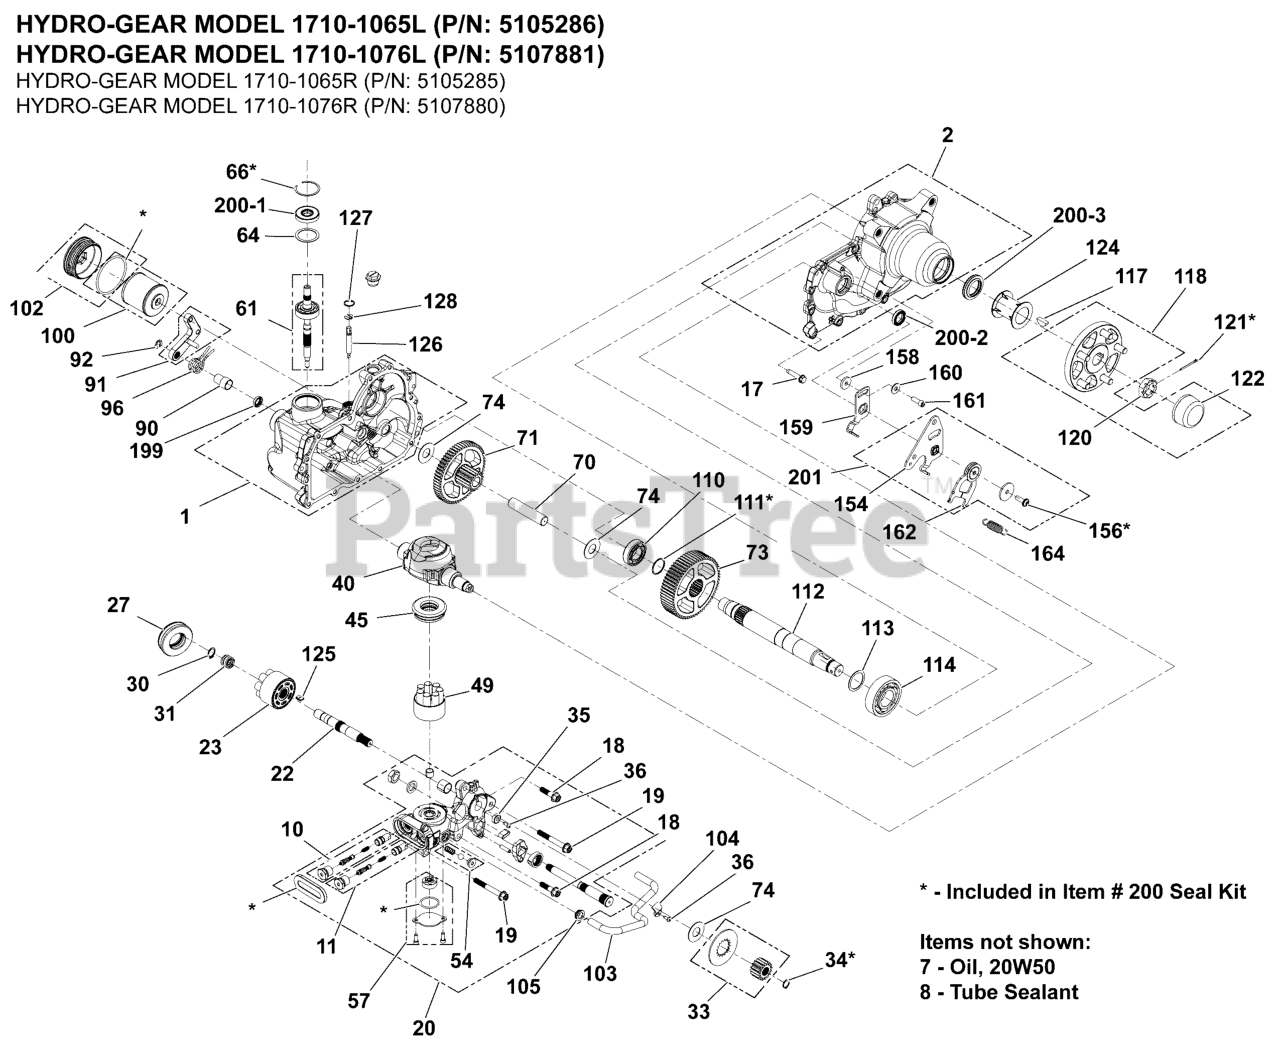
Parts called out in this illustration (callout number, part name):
1	KIT, MAIN HOUSING
2	KIT, SIDE HOUSING
7	OIL
10	KIT, SHOCK VALVE
11	KIT, SHOCK VALVE
17	SCREW, HOUSING
20	KIT, CENTER SECTION
22	SHAFT, MOTOR
27	BEARING, THRUST, MOTOR
30	RING, RETAINING
31	SPRING-CYLINDER BLOCK 2000025
33	KIT, BRAKE ROTOR, GEAR
34	RING-SNAP (44145)
35	MAGNET
36	BOLT, SELF-TAPPING
40	SWASHPLATE, MACHINED
45	BEARING, THRUST, PUMP
54	KIT, CHARGE RELIEF
57	KIT, CHARGE PUMP
61	KIT, INPUT SHAFT (BEARING & SHAFT ONLY) (SV)
64	SPACER, INPUT
66	RING, RET, INTERNAL, INPUT
70	JACKSHAFT
71	KIT, GEARS
74	WASHER, JACKSHAFT
90	SPACER, SPRING
91	KIT, BRAKE, LH
92	RETAINING RING, BRAKE ARM, ZT4400 (SV)
96	SPRING, BRAKE RETURN
100	KIT, FILTER (SV)
102	KIT, FILTER PLUG
103	TUBE, FILTER, LH
104	CLAMP, TUBE, FILTER
105	GROMMET
110	BEARING, BALL, AXLE INBOARD
111	RING, RETAINING, .125, EXTERNAL, SPRING
112	SHAFT, AXLE
113	WASHER, AXLE, SHAFT BEARING
114	BEARING, BALL, OUTBOARD
117	KEY, SHAFT, AXLE
118	KIT, HUB 5 BOLT (SV)
120	NUT, HEX 1-20 SLOTTED
121	PIN, COTTER, 9/64 X 2 EXTENDED PRONG
122	AXLE CAP, ZT5400
125	PLATE, BYPASS
126	BYPASS ROD
154	ARM, CONTROL, LH
156	TWHCS, 5/16-24 X 1.00 (PATCH)
159	ARM, NEUTRAL, LH
161	SHCS, 5/16-24 X .875 (PATCH)
162	ASSEMBLY, RTN
164	SPRING, EXTENSION RTN-44LBS, H/G 51605
199	BRAKE SHAFT SEAL, 55523, ZT4400 & ZT5400
200	KIT, SEAL (SV)
200-1	KIT, INPUT SEAL (SV)
200-2	KIT, CONTROL ARM SEAL, HG# 55526
200-3	KIT, AXLE SEAL (SV)
201	KIT, L.H. Control Arm
